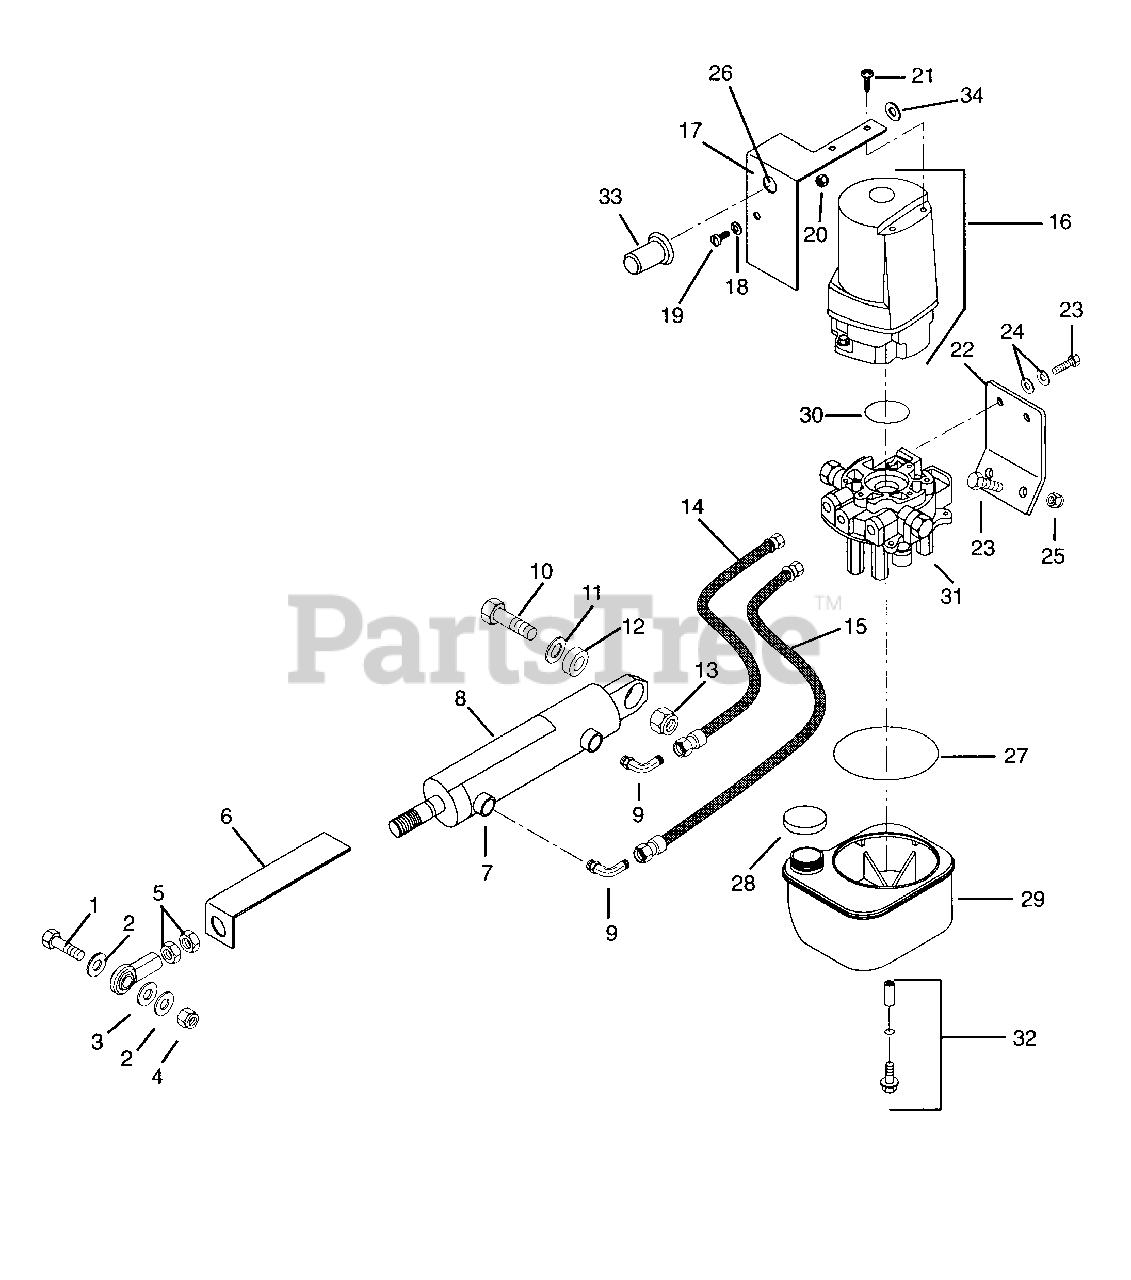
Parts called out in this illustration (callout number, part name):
1	Bolt-Hex .62-11 x 2.50 Grade 5
2	Washer-Flat-Steel .656 x 1.31 x .095
3	Rod End 5/8" Female
4	Nut-Locking-Center .62-11
5	Nut-Jam .625-18
6	Strap-Height of Cut Indicator
7	Cylinder-Hydraulic Lift
8	Decal-Height of Cut
9	Adapter 2503-4-4
10	Bolt-Hex .50-13 x 2.25 Grade 5
11	Washer-Flat-Steel .630 x 1.005 x .062
12	Bushing .516 x 1.000 x 1.050
13	Nut-Locking-Center .50-13
14	Assembly-Hose Pump to Cylinder
15	Assembly-Hose Pump to Cylinder
16	Motor Assembly
17	Switch Plate
18	Washer-Flat-Steel .281 x .620 x .065
19	Screw-Machine-Hex-Washer-Head .25-20 x .75
20	Nut-Locking-Center .25-20
21	Screw-Machine 10-24 x .75
22	Lift Pump Mounting Bracket
23	Bolt-Round Head Square Neck .38-16 x .75 Grade 2
24	Washer-Flat-Steel .406 x .812 x .065
25	Nut-Locking-Center .38-16
26	Decal-Cutting Heat Treated Adjustment
27	Reservoir Seal-O-Ring
28	Reservoir Cap
29	Reservoir Tank
31	Adapter Assembly
32	Screw-O-Ring and Spacer Assembly
33	Boot-Switch
34	Washer-Flat-Steel .505 x .880 x .072
